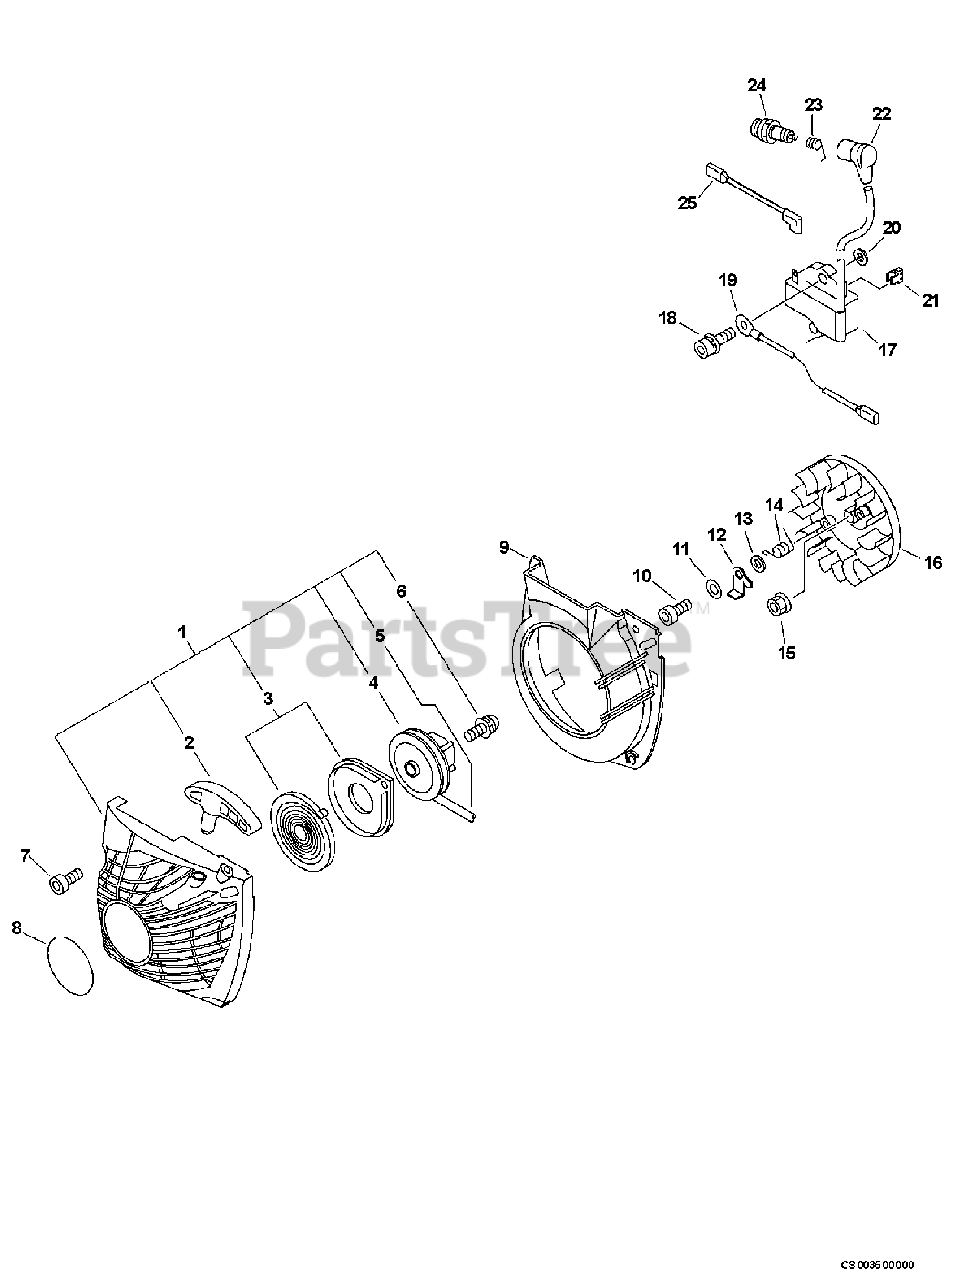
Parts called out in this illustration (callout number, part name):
1	STARTER ASSY, RECOIL - I-START
2	GRIP, STARTER
3	SPRING SET, RECOIL
4	REEL, ROPE
5	ROPE, STARTER 3.5×900
6	SCREW
7	SCREW TAPPING 5×20
8	LABEL, ECHO
9	COVER, FAN
10	BOLT 5×14
11	WASHER 5.5×12×0.8
13	SPACER 5.2×8×2.1
14	SPRING, TORSION
15	NUT, FLANGE M8
16	FLYWHEEL
17	COIL, IGNITION
18	BOLT 5×20
19	LEAD - GROUND L= 140
20	WASHER 5.2×12×3
22	CAP, SPARK PLUG
23	TERMINAL, SPARK PLUG
24	SPARK PLUG - BPM8Y
24	SPARK PLUG - BPMR8Y
25	LEAD - IGNITION L= 172
